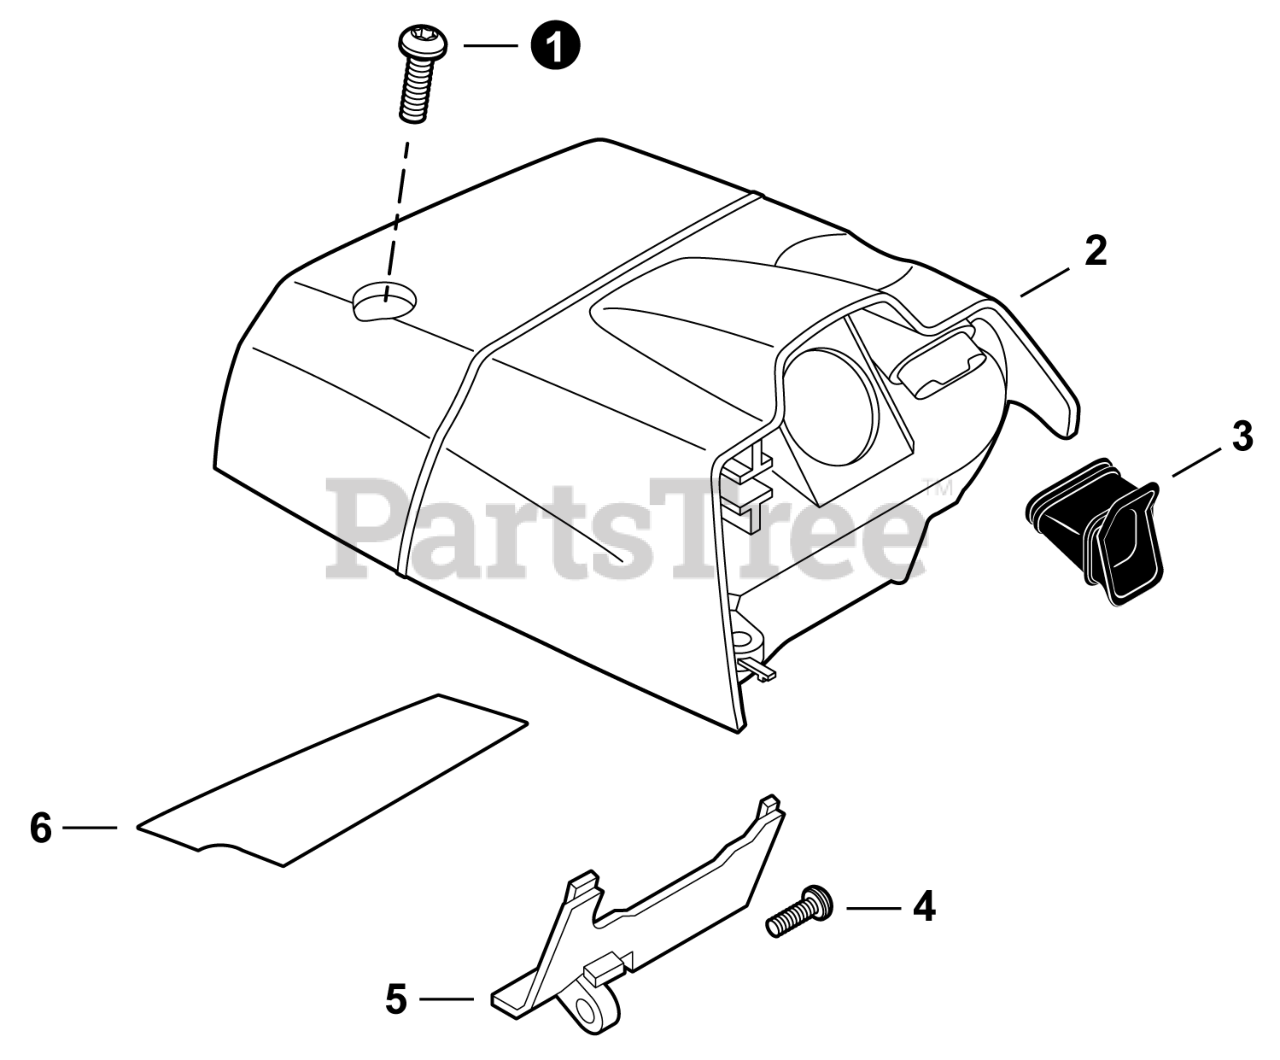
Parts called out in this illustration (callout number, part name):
1	BOLT, TORX 5x16
2	COVER, ENGINE
3	PIPE, INTAKE
4	BOLT, TORX 5x16
5	GUIDE, AIR
6	SHIELD, HEAT 75x32x0.15
